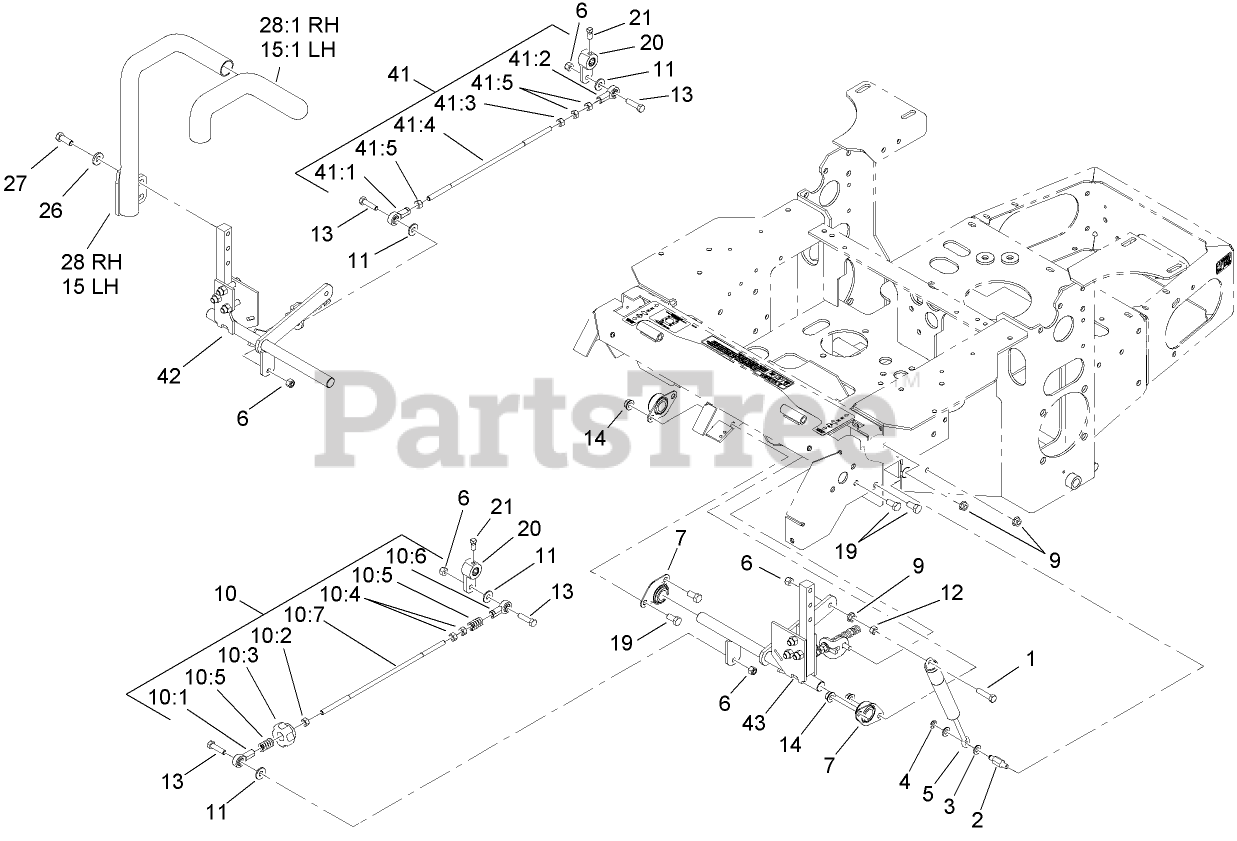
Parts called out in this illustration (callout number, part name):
1	SCREW-HH
2	PIN-DAMPER
3	WASHER-PLAIN
4	RING-RETAINING, EXT
5	DAMPER-CONTROL, MOTION
6	NUT-LOCK, NI
7	BEARING-FLANGE, SIDE
9	NUT-HF
10	TRACKING ROD ASM
10:1	BALLJOINT-RH
10:2	NUT-HEX
10:3	KNOB-TRACKING
10:5	SPRING-COMPRESSION
10:6	BALLJOINT-LH
10:7	Link-Rod, Tracking
11	WASHER-FLAT
12	NUT-HEX
13	SCREW-HH
14	NUT-HHF, WHIZ
15	LH LEVER ASM
15:1	Grip-Control, Motion
19	SCREW-HH
20	ARM-CONTROL
21	SCREW-SET
26	WASHER-BELLEVILLE
27	SCREW-HH
28	RH LEVER ASM
28:1	Grip-Control, Motion
41	TRACKING ASM
41:1	BALLJOINT-RH
41:2	BALLJOINT-LH
41:4	Link-Rod, Tracking
41:5	NUT-HEX
42	RH MOTION CONTROL ASM
43	LH MOTION CONTROL ASM
